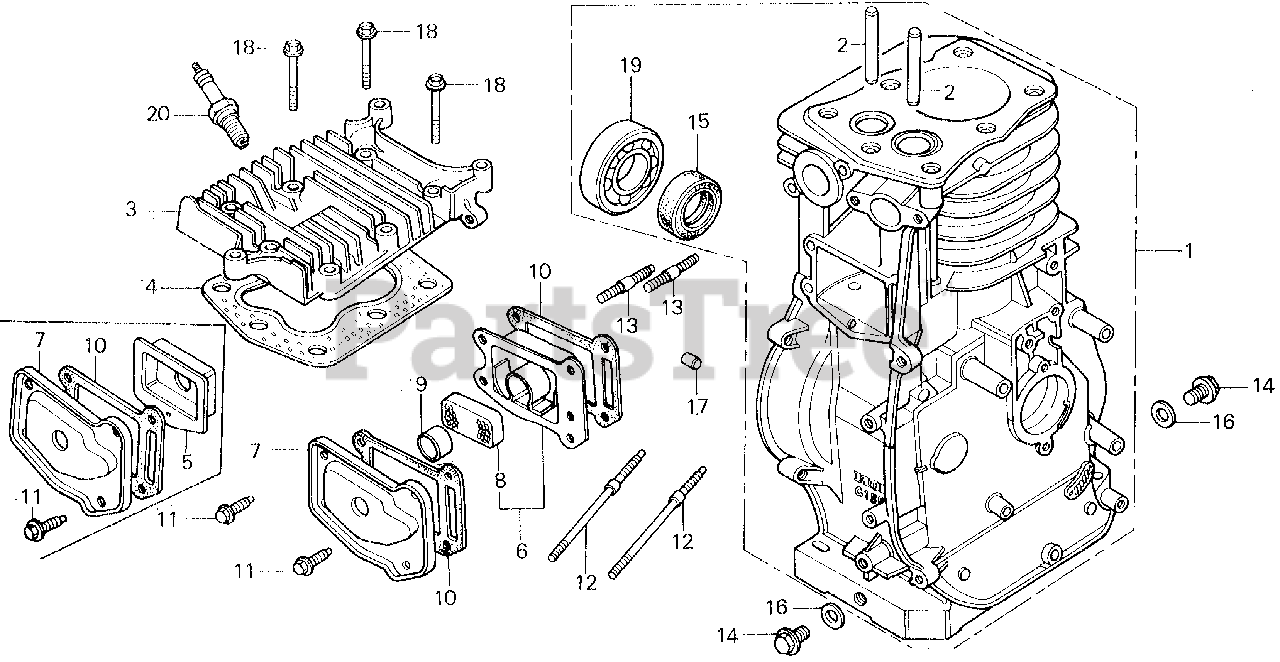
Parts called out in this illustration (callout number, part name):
1	CYLINDER ASSY.
2	GUIDE, VALVE (OS)
3	CYLINDER HEAD
4	GASKET, CYLINDER HEAD
5	CASE, BREATHER
6	CASE, BREATHER
7	COVER, TAPPET ROOM
8	FILTER, BREATHER
9	SEAL, BREATHER
10	GASKET, TAPPET COVER
11	BOLT, FLANGE (6X12) (CT200)
12	BOLT, STUD (6X96)
13	BOLT, STUD (8X35)
14	BOLT, DRAIN PLUG
15	OIL SEAL (25X41X6)
16	WASHER, DRAIN PLUG (12MM)
17	PIN A, DOWEL (8X14)
18	BOLT, FLANGE (8X45)
19	BEARING, RADIAL BALL (6205)
20	SPARK PLUG (BR-4HS) (NGK)
20	SPARK PLUG (W14FR-U) (DENSO)
